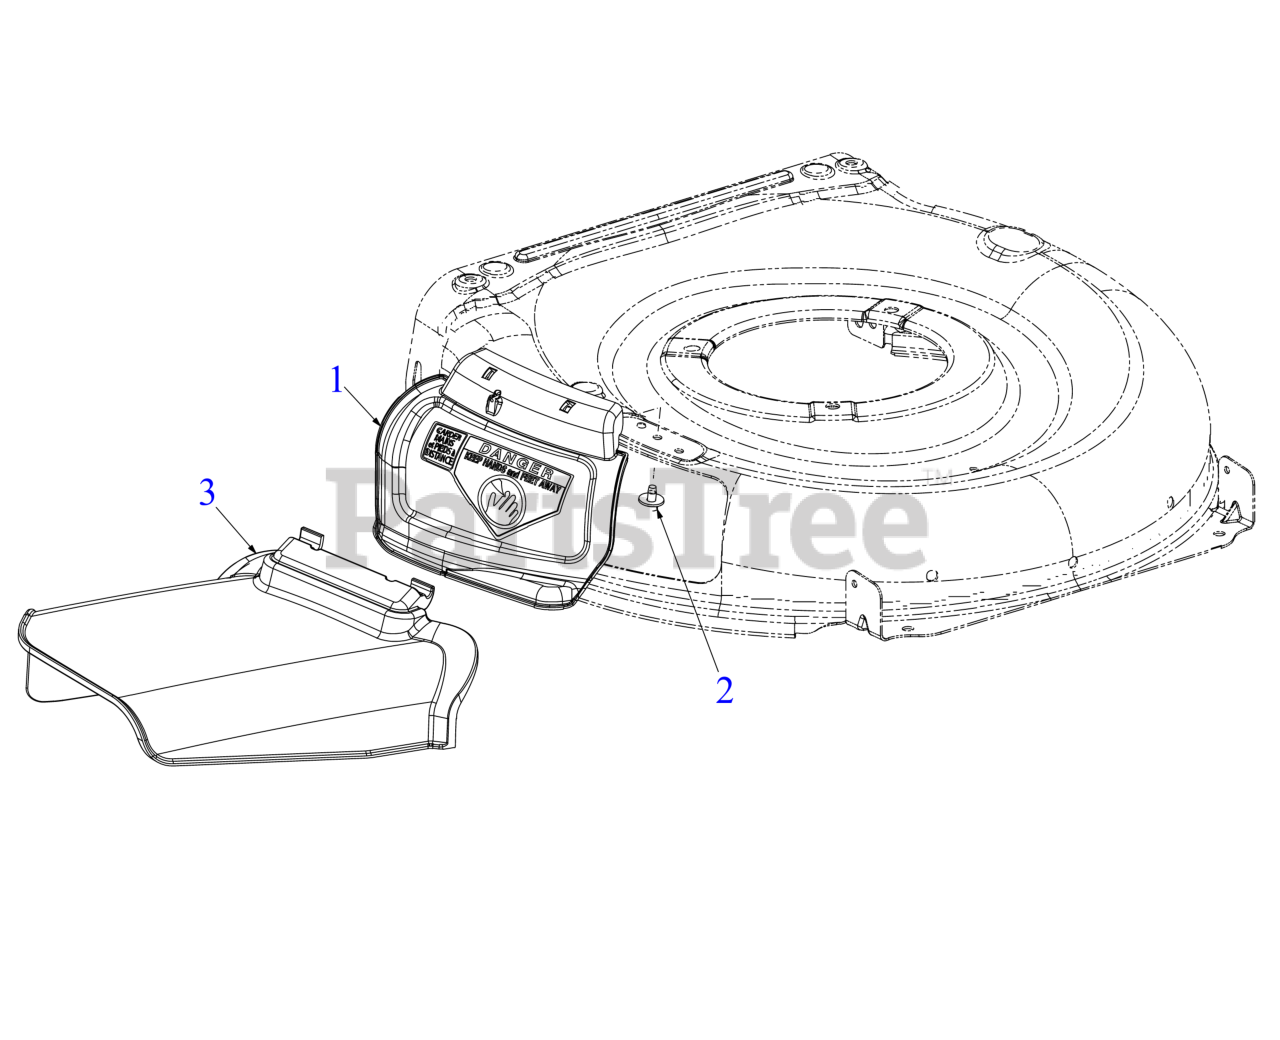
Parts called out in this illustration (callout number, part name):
1	21" MULCH PLUG (HINGED)
2	SCREW 1/4-20 x .50
3	SIDE DISCHARGE CHUTE
